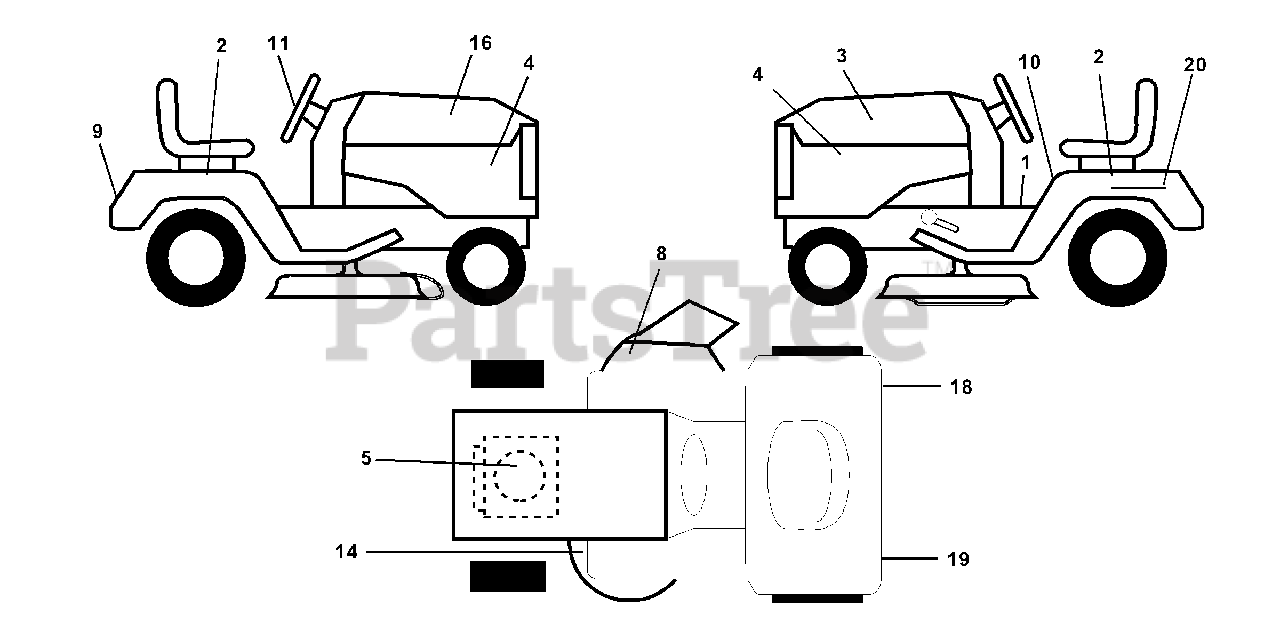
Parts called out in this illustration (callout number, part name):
2	Decal Fender Side
3	Decal Hood LH
4	Decal Side Panel Logo
5	Decal HP Engine
8	Decal Warning Mult-Language
9	Decal Fender Logo
10	Decal Fender Danger E/F
11	Decal Ins Strg Whl
14	Decal V-Belt Schematic
16	Decal Hood Rh
18	Decal Fender Reflector RH
19	Decal Fender Reflector LH
20	Decal Bat Dan/Psn
